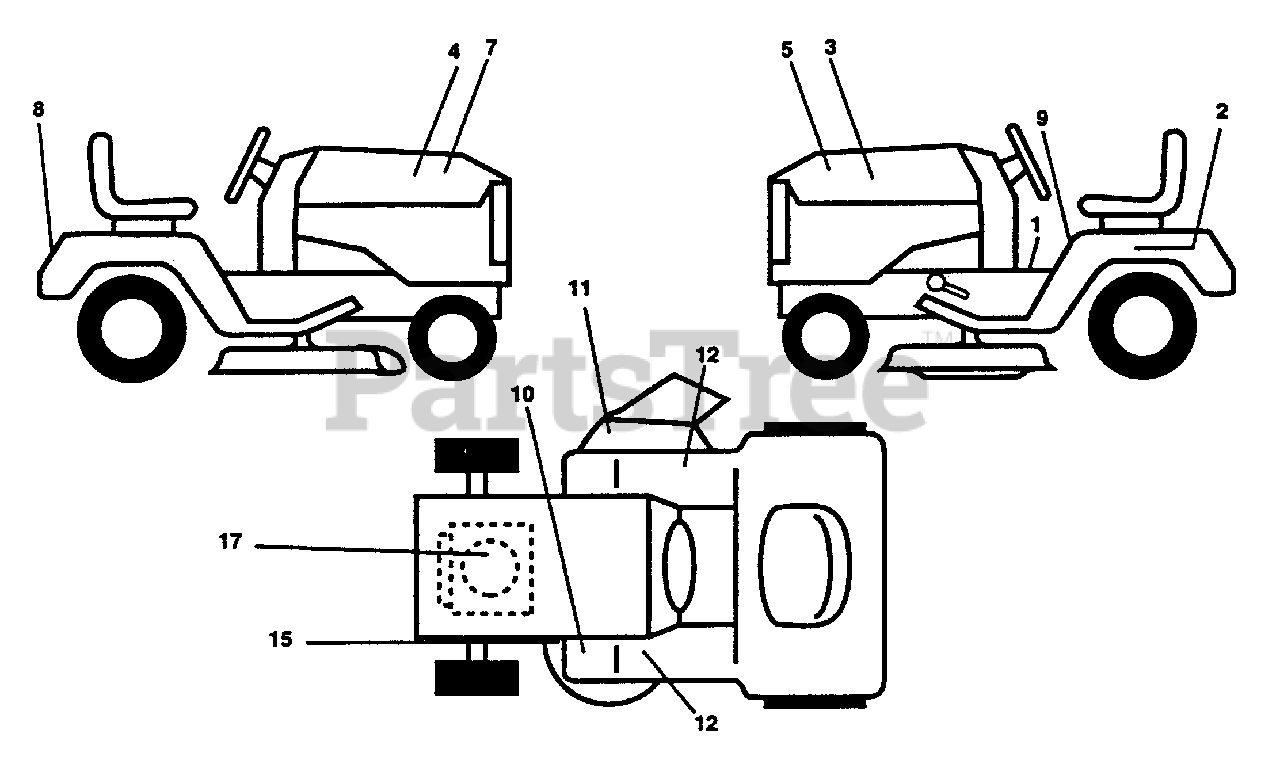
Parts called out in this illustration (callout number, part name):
1	Decal Instruction Dash Eng/fr
2	Decal Caution Battery Fr/ger
3	Decal Hood LH
4	Decal Hood RH
5	Decal Ins Hd LH
7	Decal Ins Hd RH
8	Decal Fender Logo
9	Decal Caution Fender Eng/fr
10	Decal Clutch/brake Eng/fr
11	Decal Warning Multi-Language
12	Pad Footrest Ribbed
15	Decal V-Belt Schematic
17	Decal HP Engine
